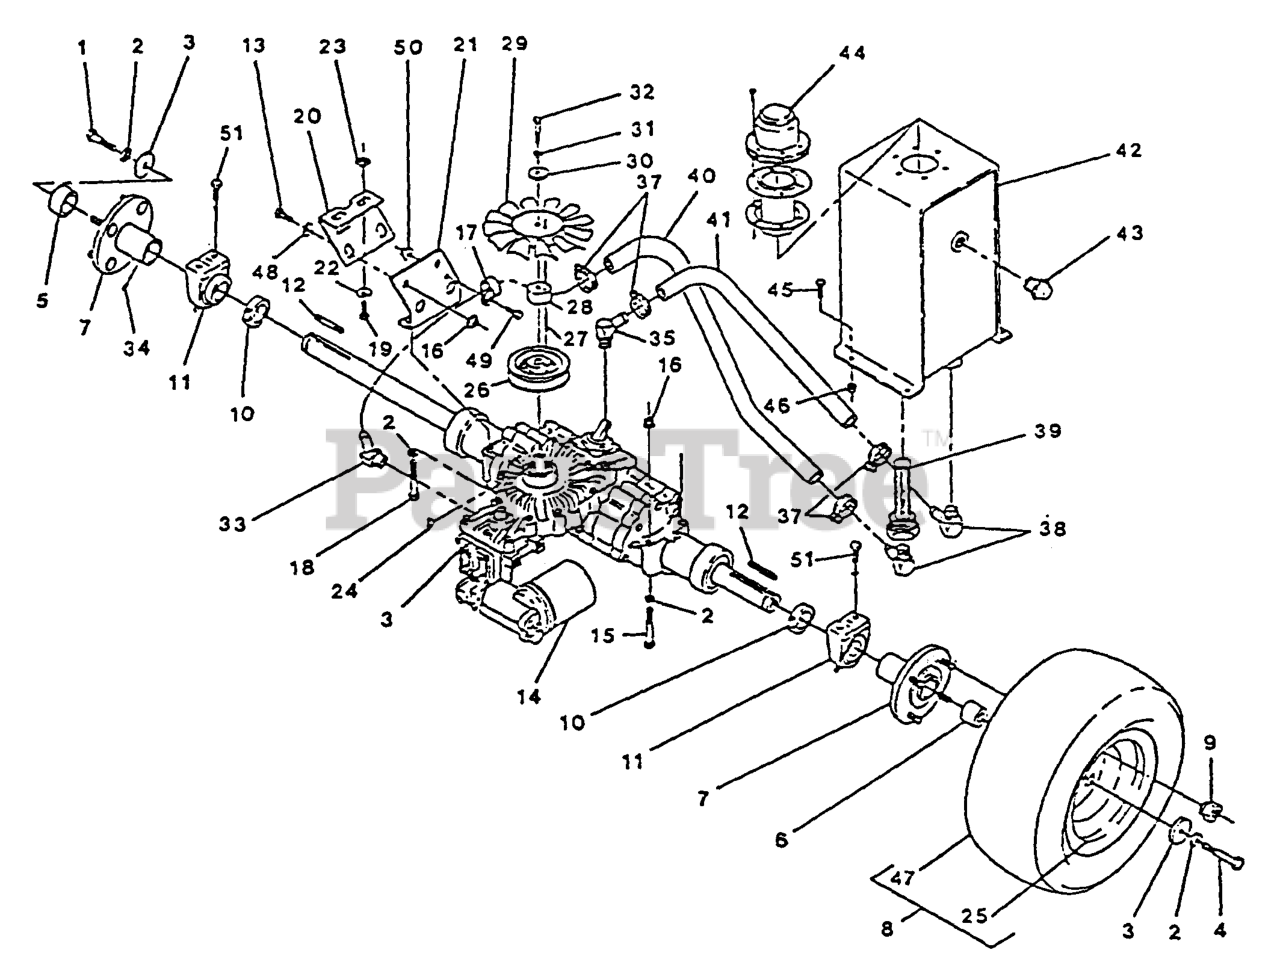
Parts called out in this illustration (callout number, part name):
8	WHEEL AND TIRE ASM
11	BEARING,PILLOW BLOCK
12	KEY,MACH HRD
28	SPACER,FAN
29	FAN,7"OD/10BLADE
30	WASHER-RETAINER, PULLEY
31	WASHER-LOCK
33	ELBOW-45DEGOR/HSEBRB
37	CLAMP-HOSE
40	HOSE,HYDRAULIC 16.5
41	HOSE,HYDRAULIC 8.0
43	OIL EYE,HYDRAULIC TANK
44	BREATHER,FILLR & CAP
